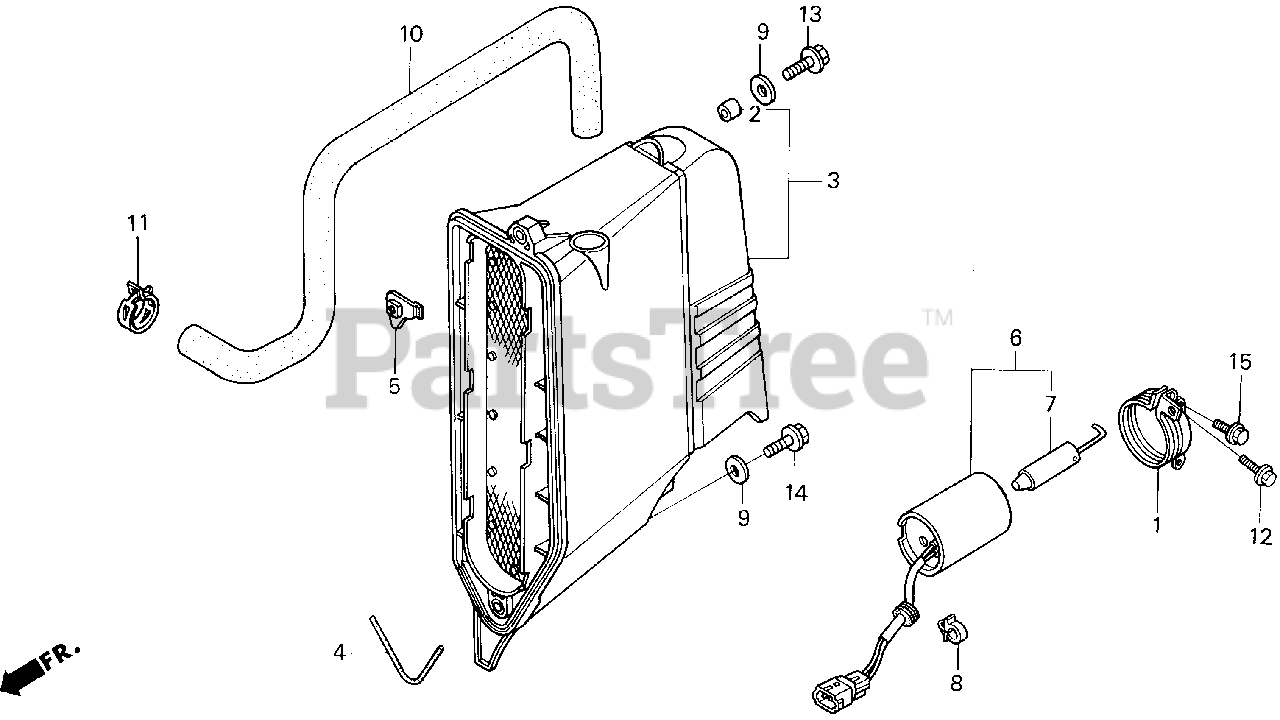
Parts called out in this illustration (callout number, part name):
1	STAY, SOLENOID
2	COLLAR, DISTANCE
3	COVER, MUFFLER
4	GASKET, MUFFLER COVER
5	NUT, MUFFLER COVER
6	SOLENOID ASSY., REMOTE CHOKE
7	PLUNGER, SOLENOID
8	HOLDER, ROD (6MM)
9	WASHER (6.5X18)
10	TUBE, BREATHER
11	CLAMP, TUBE (D17)
12	BOLT, FLANGE (6X14)
13	BOLT, FLANGE (6X25)
14	BOLT, FLANGE (6X40)
15	BOLT, FLANGE (6X12)
